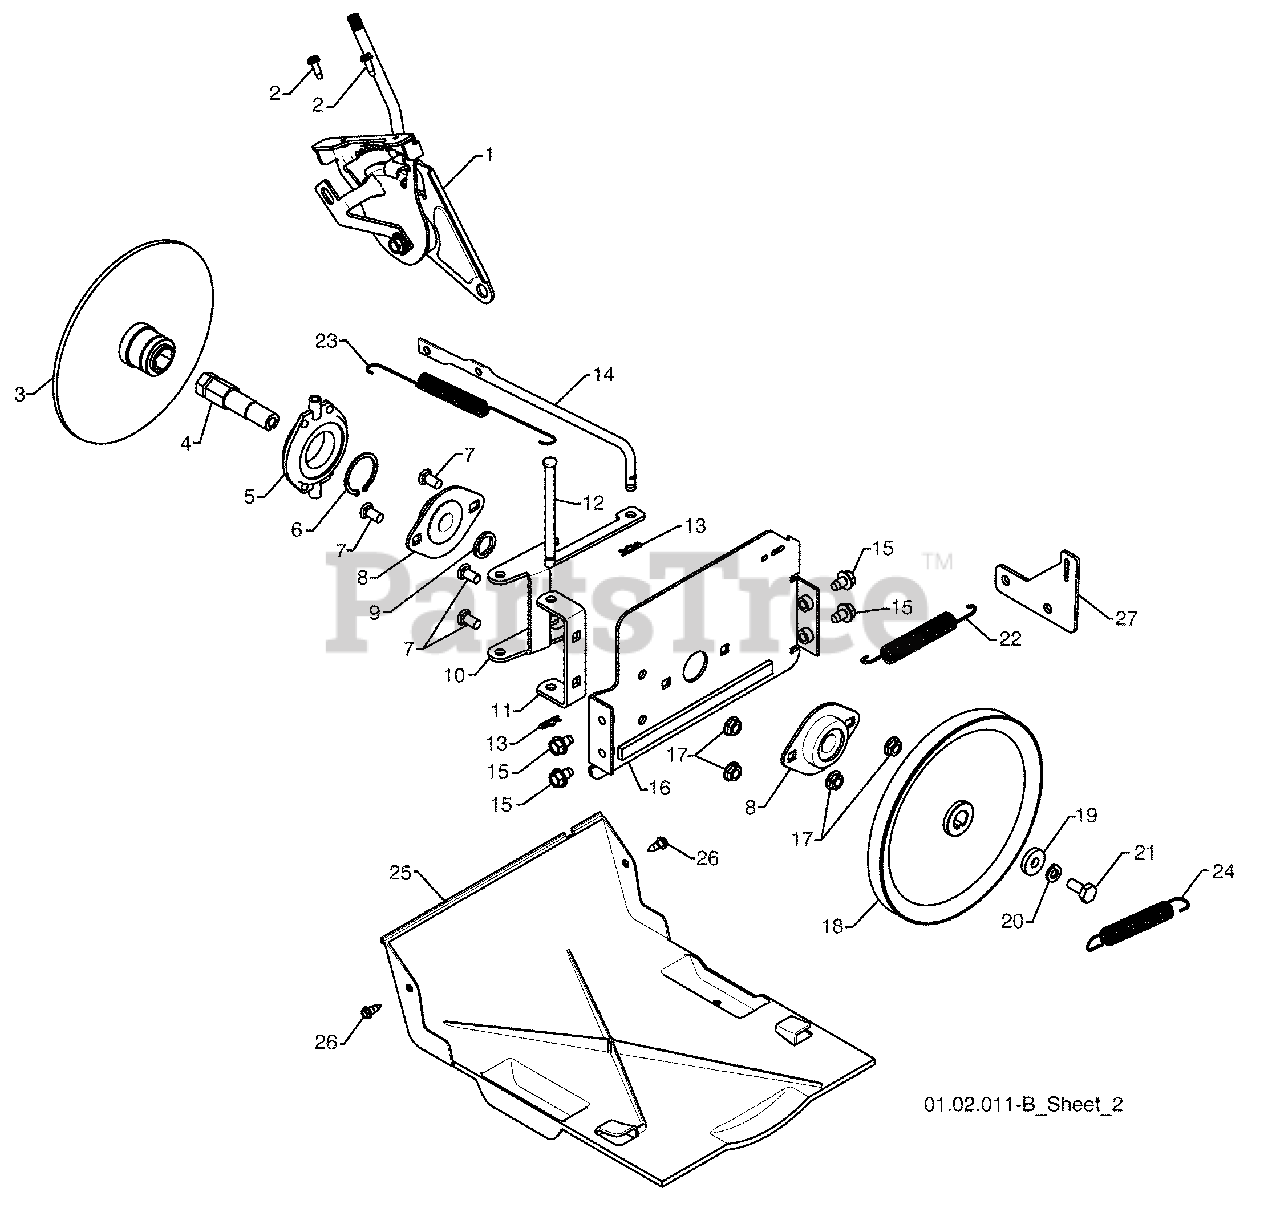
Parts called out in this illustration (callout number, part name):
1	SPEED SELECTOR HEAD ASSEMBLY
2	SCREW 10-24 X .625
3	DRIVE PLATE WELDMENT
5	TRUNNION BEARING ASSEMBLY
6	RETAINER
7	CARRIAGE BOLT 5/16-18 X .625
8	FLANGE BEARING
10	LEVER SHIFTER PLATE
11	SHIFTER SUPPORT BRACKET
14	CLUTCH ROD
15	BOLT 5/16-18 X .500
16	DRIVE MOUNT PLATE
17	NUT 5/16-18
18	TRACTION PULLEY
20	LOCKWASHER 5/16
21	SCREW 5/16-18 X .750
22	TRACTION SPRING
23	RETURN SPRING
24	BRAKE SPRING
25	BOTTOM PAN
26	SCREW 10-24 X .625
27	TRACTION SPRING BRACKET
